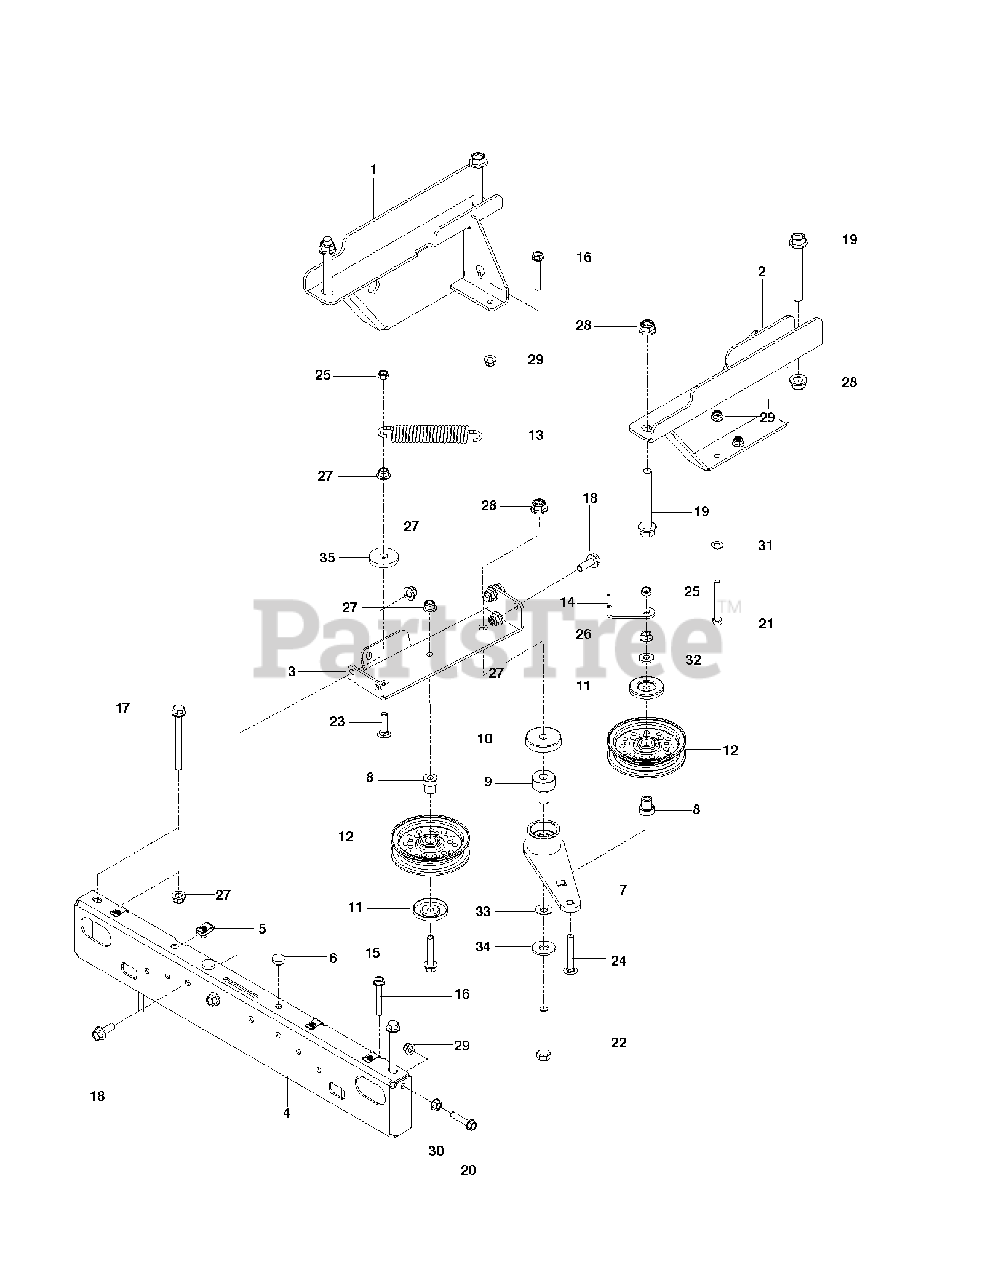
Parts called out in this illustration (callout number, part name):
1	MOUNT.ZT3400.RT.BLACK
2	MOUNT.ZT3400.LT.BLACK
3	MOUNT IDLER BLK
4	MOUNT FT ZT3400 BLK
5	U-CLIP 5/16-18 NUT RETAINER
6	GROMMET, BUMPER
7	ARM, IDLER, STEEL, W/BGS
8	PIVOT, IDLER
9	PIVOT, BEARING
10	SHIELD, DUST
11	DUST SHIELD
12	IDLER PULLEY
13	SPRING, EXTENSION
14	BRACKET, SPRING
15	HHFS 3/8-16 X 2.0 GD 5
16	HHFS 5/16-18 X 2.25 GD 5
17	HHFS 3/8-16 X 4 GR5 ZD
18	HHFS 3/8-16 X 1 GRD 5 ZD
19	HHFS 1/2-13 X 4.0 GD8 ZD
20	HHFS 5/16-18 X 1.5 GD 5
21	HCS 5/16C X 2-3/4
22	HCS 1/2C X 3 1/4
23	RHSNB, 3/8-16 X 1-1/2
24	CARRIAGE BOLT 3/8-16 X
25	NUT HEX 3/8-16 NYLON, THIN
26	NUT 3/8C WHIZ
27	NUT 3/8-16 HEX FLG NYLOC ZD
28	NUT, 1/2-13 HEX FLG NYLOC ZD
29	5/16-18 NYLOC FLANGE NUT
30	NUT 5/16C WHIZ
31	FLAT WASHER 5/16 SAE
32	WASHER, 3/8 THICK
33	CONTACT BELLSPR 1/2
34	WASH USS FLAT 1/2
35	SPINDLE WASHER
